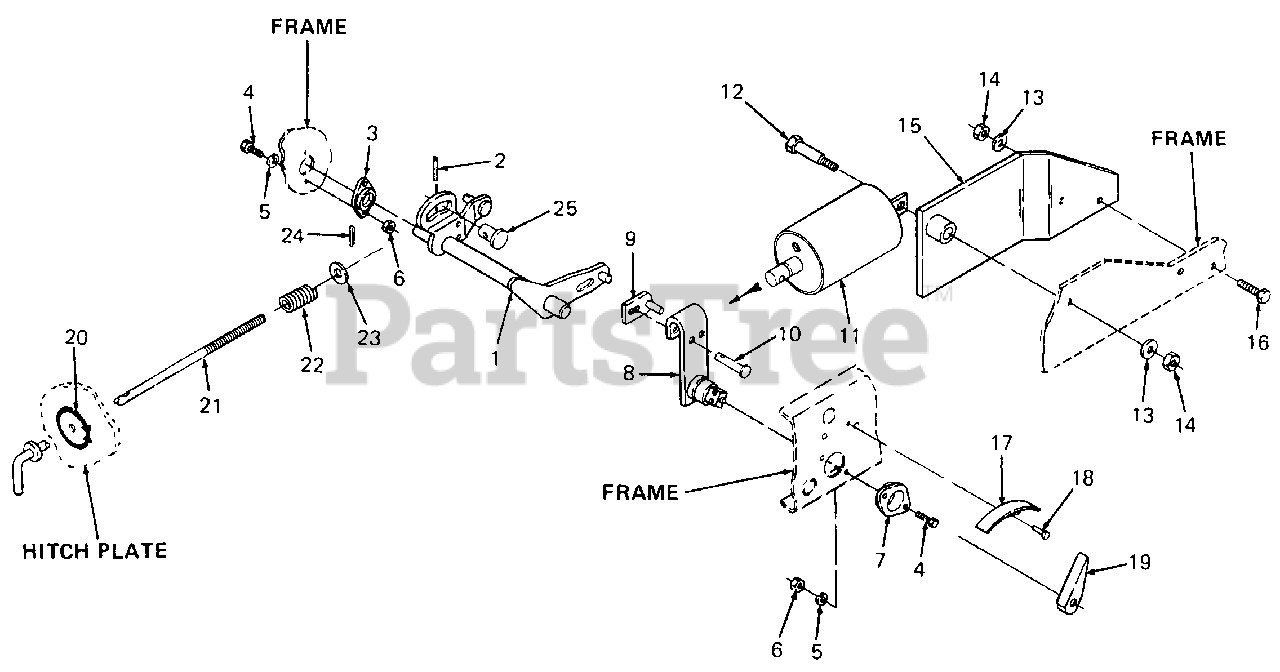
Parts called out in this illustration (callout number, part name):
3	Bushing, Lift, LH
4	Screw, Hex Cap, 1/4-20 X .75 Lg GR5
5	Washer, Lock, 1/4
6	Nut, Hex, 1/4-20 GR5
7	Bushing, Lift, RH
8	Bracket Assy, Lift
9	Pin Assy, Lift
10	Pin, Clevis, 1/2 Dia X 2.172 Lg
11	Cylinder, Hydraulic
12	Bolt, Shoulder
13	Washer, Flat, .531 X 1.06 X .134 Thk
14	Nut, Hex Center Lock, 1/2-13 GR5
15	Bracket, Cylinder
16	Screw, Hex Cap, 1/2-13 X 1.25 Lg GR5
17	Bracket, Height Indicator
18	Rivet, .156 Dia X .250 Lg
19	Indicator, Height
20	Graphic, Down Stop Adjustment
21	Rod, Down Stop Adjustment
22	Spring, Compression, .501 X .75 X 1.00 Lg
23	Washer, Flat, .656 X 1.312 X .074 Thk
24	Pin, Internal Cotter
25	Clevis, .750 X 1.00 Lg
